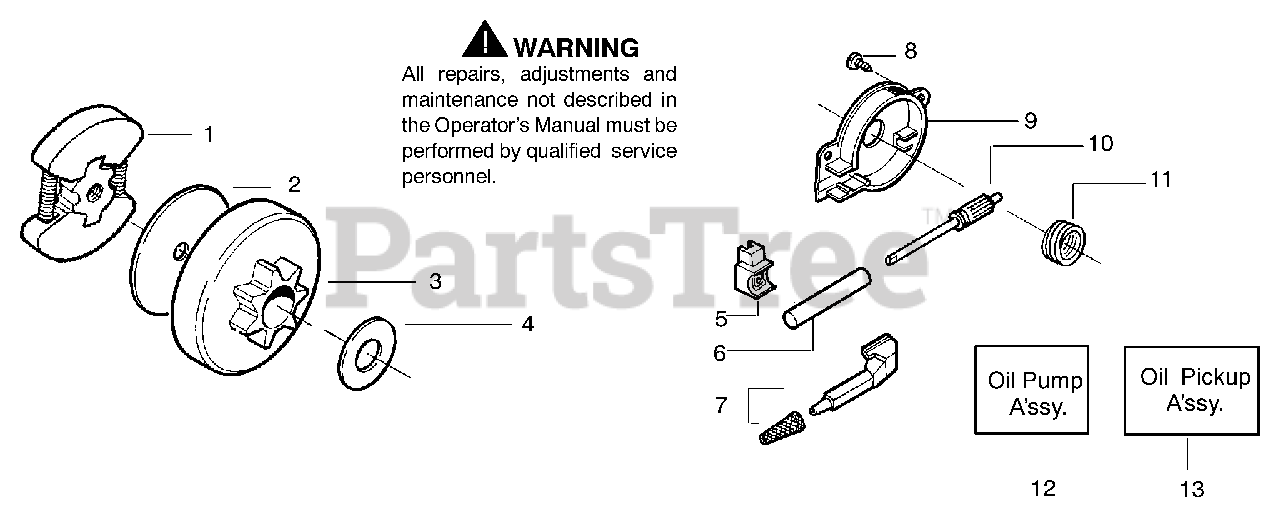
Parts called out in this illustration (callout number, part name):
1	Assy-Clutch
2	Washer-Clutch
3	Assy-Clutch Drum w/Bearing
4	Washer-Thrust
5	Seal-Oil
6	Barrel-Oil Pump
7	Assy-Oil Pick--Up and Screen
9	Housing-Oil Pump
10	Assy-Plunger & Gear
11	Worm-Oil Pump
12	Assy-Oil Pump
13	Assy-Oil Pickup
